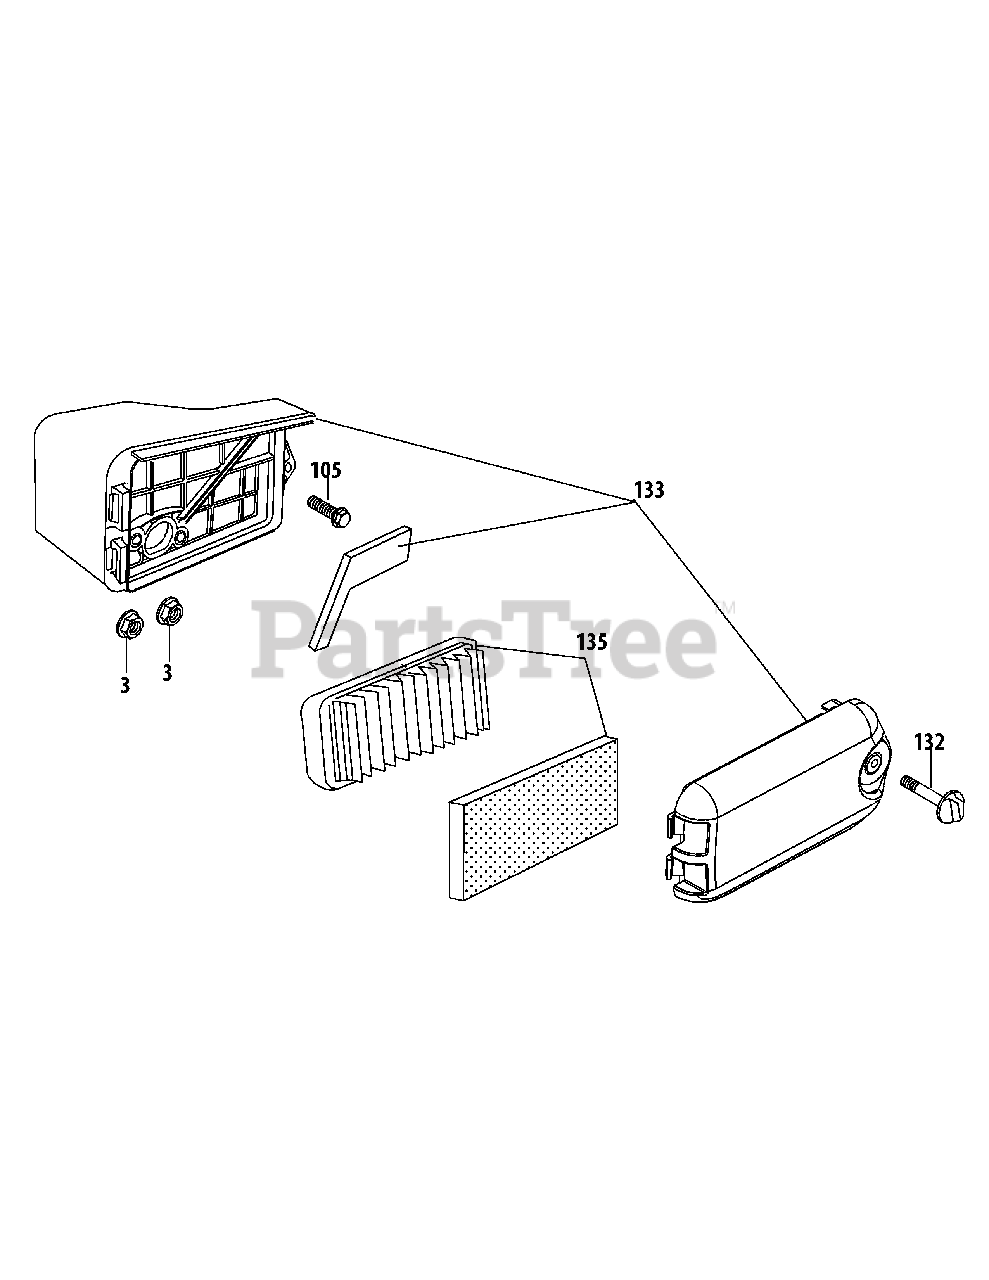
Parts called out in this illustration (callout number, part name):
3	Nut M6X10mm
105	Bolt M6X35
132	Air Filter Cover Thumb Screw
133	Air Cleaner Housing Ass'y Comp
135	Air Cleaner Elements, Filter Kit
